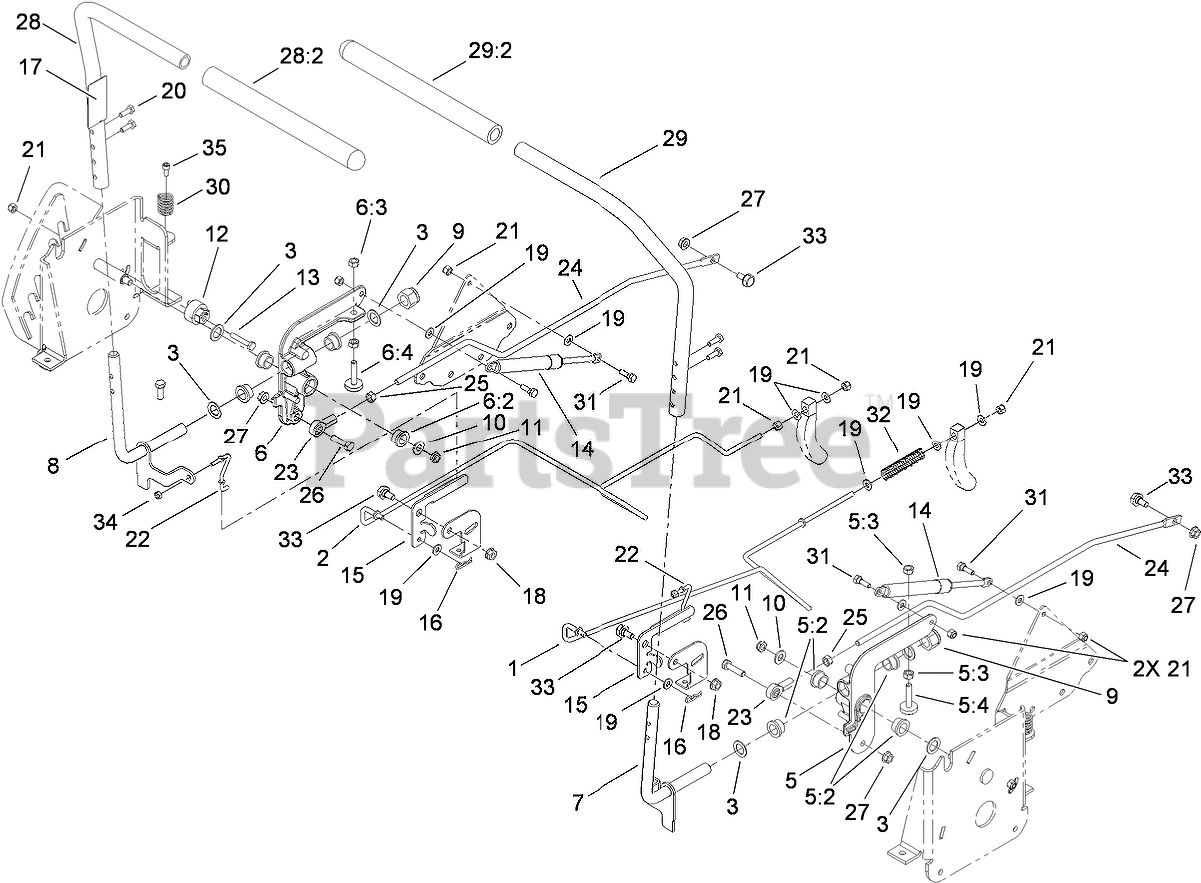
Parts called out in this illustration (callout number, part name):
1	ROD-BRAKE, LH
2	ROD-BRAKE, RH
3	WASHER-THRUST
5	LH ACTIVATOR ARM ASM
5:2	BUSHING
5:3	NUT-HEX
5:4	STOP-ADJUSTMENT
6	RH ACTIVATOR ARM ASM
6:2	BUSHING
6:3	NUT-HEX
6:4	STOP-ADJUSTMENT
7	LH PIVOT SHAFT ASM
8	RH PIVOT SHAFT ASM
9	NUT-LOCK, NI
10	WASHER-FLAT
11	NUT-LOCK, NI
12	ECCENTRIC
13	SCREW-HH
14	Damper-Control, Motion
15	BELLCRANK
16	PIN-COTTER
18	NUT-HF
19	WASHER-FLAT
20	SCREW-HH
21	NUT-LOCK, NI
22	LINK-BRAKE
23	BALLJOINT-RH
24	ROD-HYDRO
25	NUT-HEX
26	SCREW-HH
27	NUT-HF
28	RH CONTROL HANDLE ASM
28:2	GRIP-CONTROL, MOTION
29	LH CONTROL HANDLE ASM
29:2	GRIP-CONTROL, MOTION
30	SPRING-COMPRESSION
31	BOLT-SHOULDER
32	SPRING-COMPRESSION
33	BOLT-SHOULDER
34	NUT-LOCK, NI
35	SCREW-HSH
